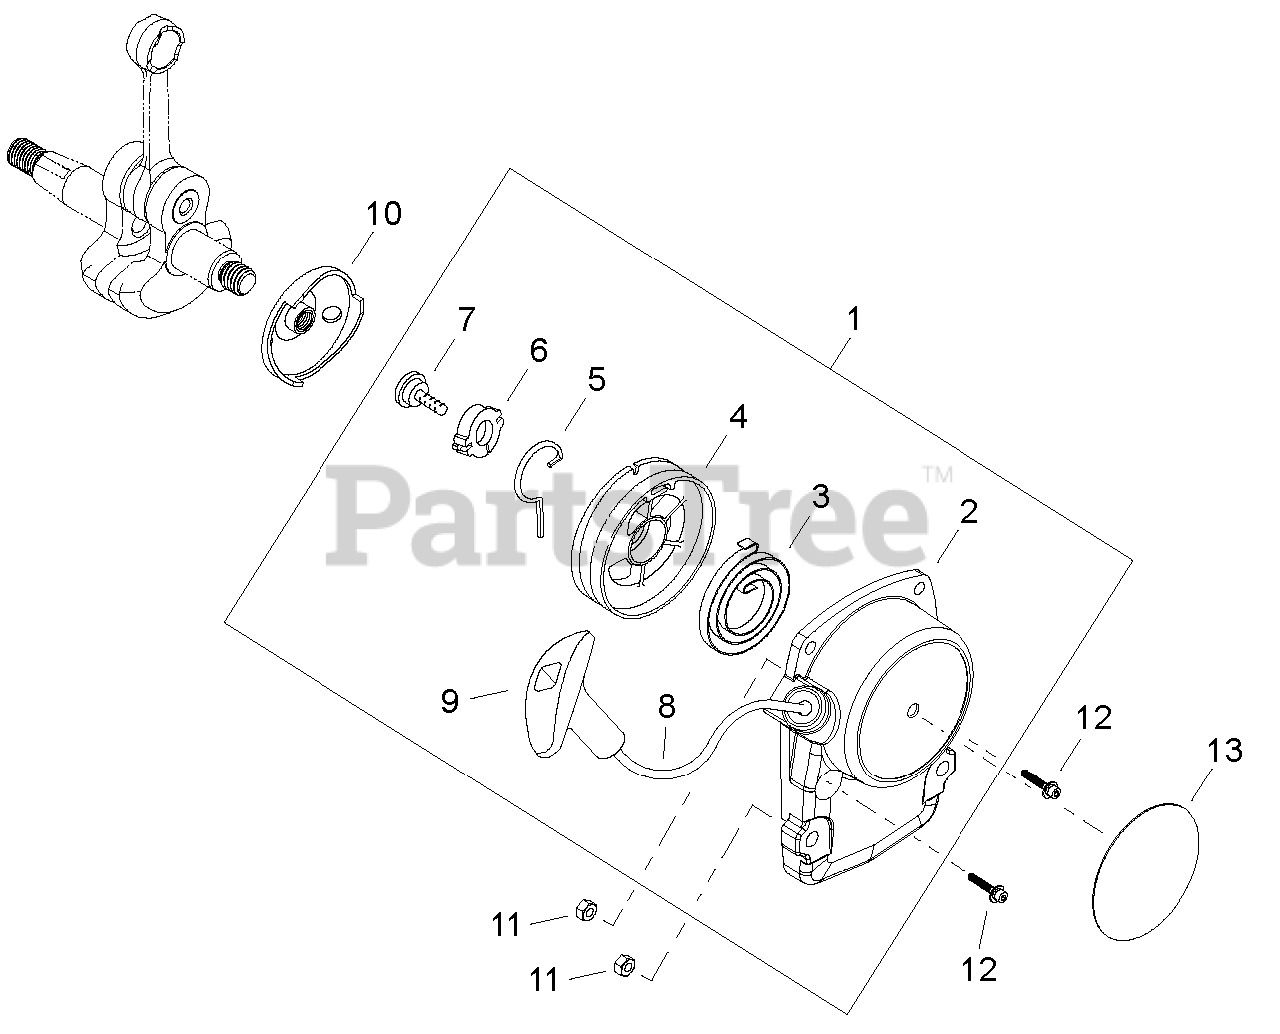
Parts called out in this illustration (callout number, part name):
2	CASE, STARTER
3	SPRING, REWIND
4	REEL, ROPE
4-1	STARTER ASSY
5	CATCHER, PAWL
6	WASHER - 5
7	SCREW - 5
8	ROPE, STARTER
9	GRIP, STARTER
10	STARTER PAWL ASSY
11	NUT - 5
12	SCREW - 4X16
13	LABEL - MODEL AHS242
